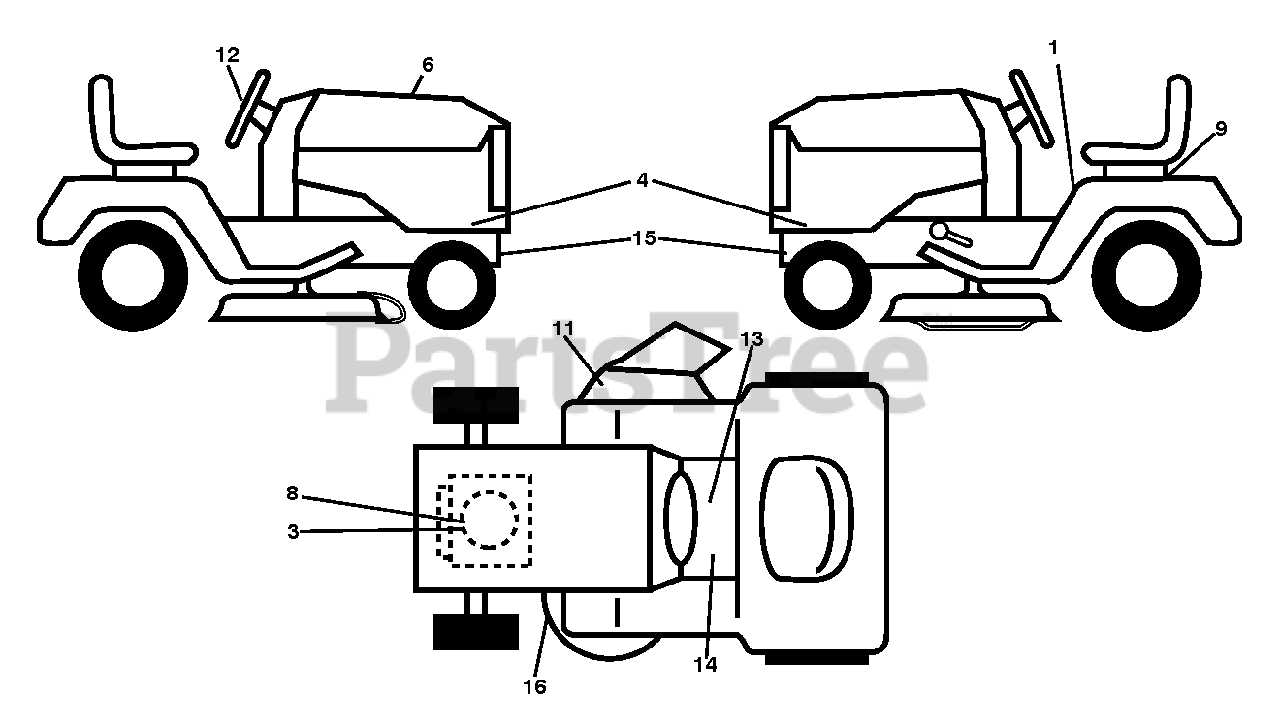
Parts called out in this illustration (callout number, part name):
9	DECAL BTRY SYMBOLS
11	DECAL.WARN.DFLCTRCTF
16	DECAL.V.BELT.30
